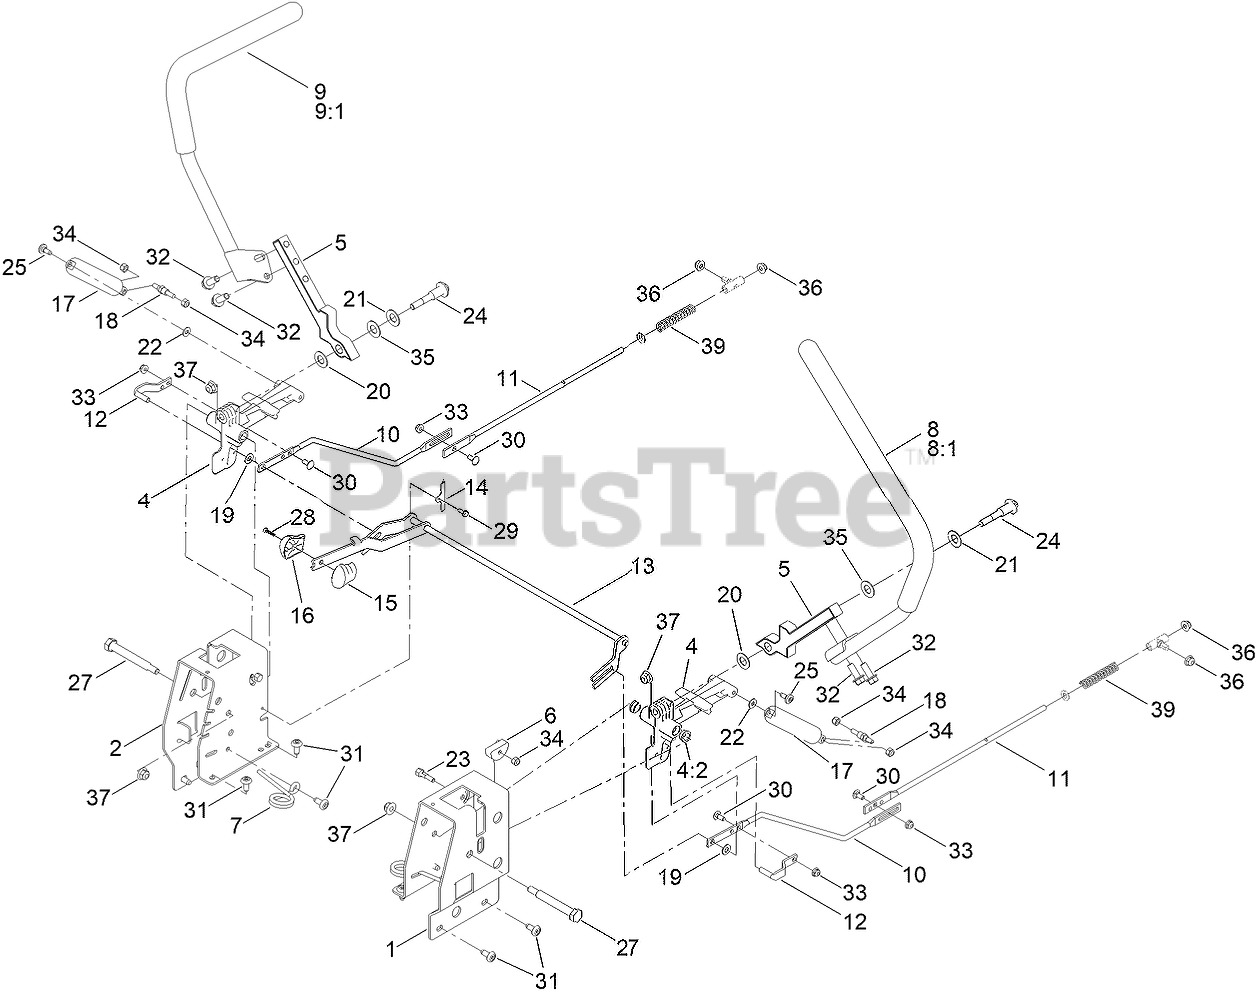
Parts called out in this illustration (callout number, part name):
1	PLATE-CONTROL BOX, LH
2	PLATE-CONTROL BOX, RH
4	ACTUATOR ARM ASM
4:2	BUSHING-FLANGE
5	ARM-CONTROL
6	ECCENTRIC
7	SPRING-TORSION
8	HANDLE-CONTROL, LH
9	HANDLE-CONTROL, RH
10	ROD-HYDRO, FRONT
11	ROD-HYDRO, REAR
12	PIN-ROD, HYDRO
13	SPEED CONTROL ASM
14	PLATE-RETAINER
15	KNOB-RH
16	KNOB-LH
17	DAMPER-NON CAVITATING
18	STUD-DAMPER
19	SPACER-NYLON
20	WASHER-NYLON
21	WASHER-BELLEVILLE
22	WASHER
23	BOLT-PIVOT, ECCENTRIC
24	BOLT-PIVOT
25	SCREW-SHOULDER
27	BOLT-PIVOT
28	SCREW-PPH
29	SCREW-TAPTITE
30	SCREW-CARR
32	SCREW-HHF
33	NUT-HF
34	NUT-LOCK, NI
35	WASHER
36	NUT-HF
37	NUT-HF, NI
39	BOLT-SHOULDER,HFH
